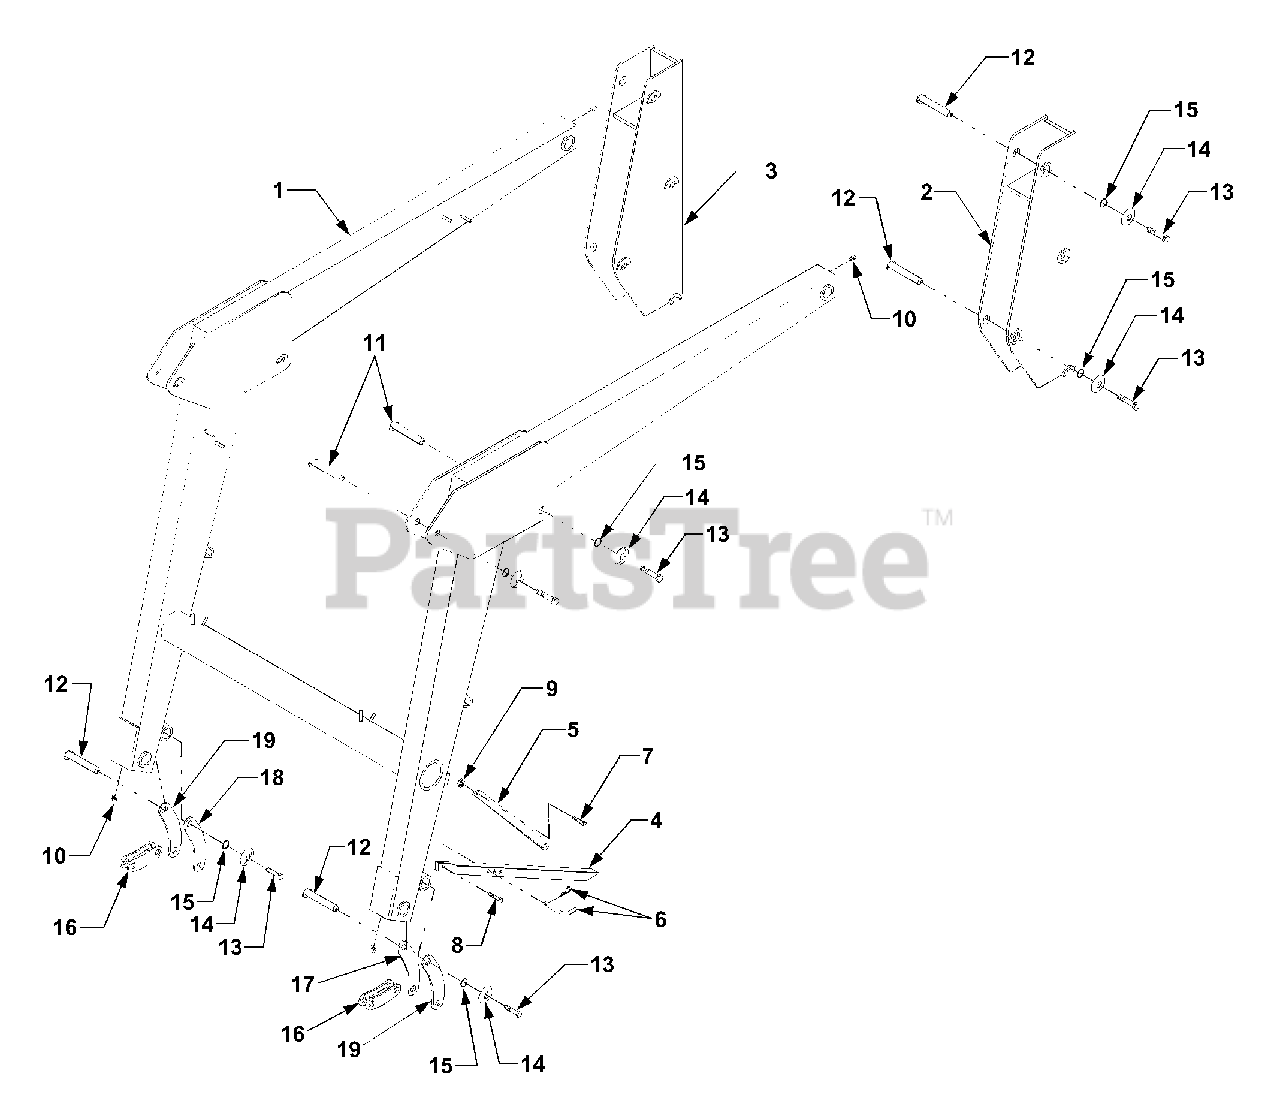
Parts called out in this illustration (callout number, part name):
1	Boom Assembly
2	Bearing Box, LH
3	Bearing Box, RH
5	Parking Leg Brace
6	Bent Pin W/Hitch Pin Clip
7	Hex Cap Screw, 3/8" x 1 1/2"
8	Hex Cap Screw, 3/8" x 1 1/4"
9	Hex Lock Nut, 3/8"
10	Grease Fitting
11	Pivot Pin, 1" x 82mm
12	Pivot Pin, 1" x 99mm
13	Hex Cap Screw, 5/16" x 3/4"
16	Bucket Linkage Assembly
17	Boom Linkage Assembly, LH
18	Boom Linkage Assembly, RH
19	Boom Linkage
